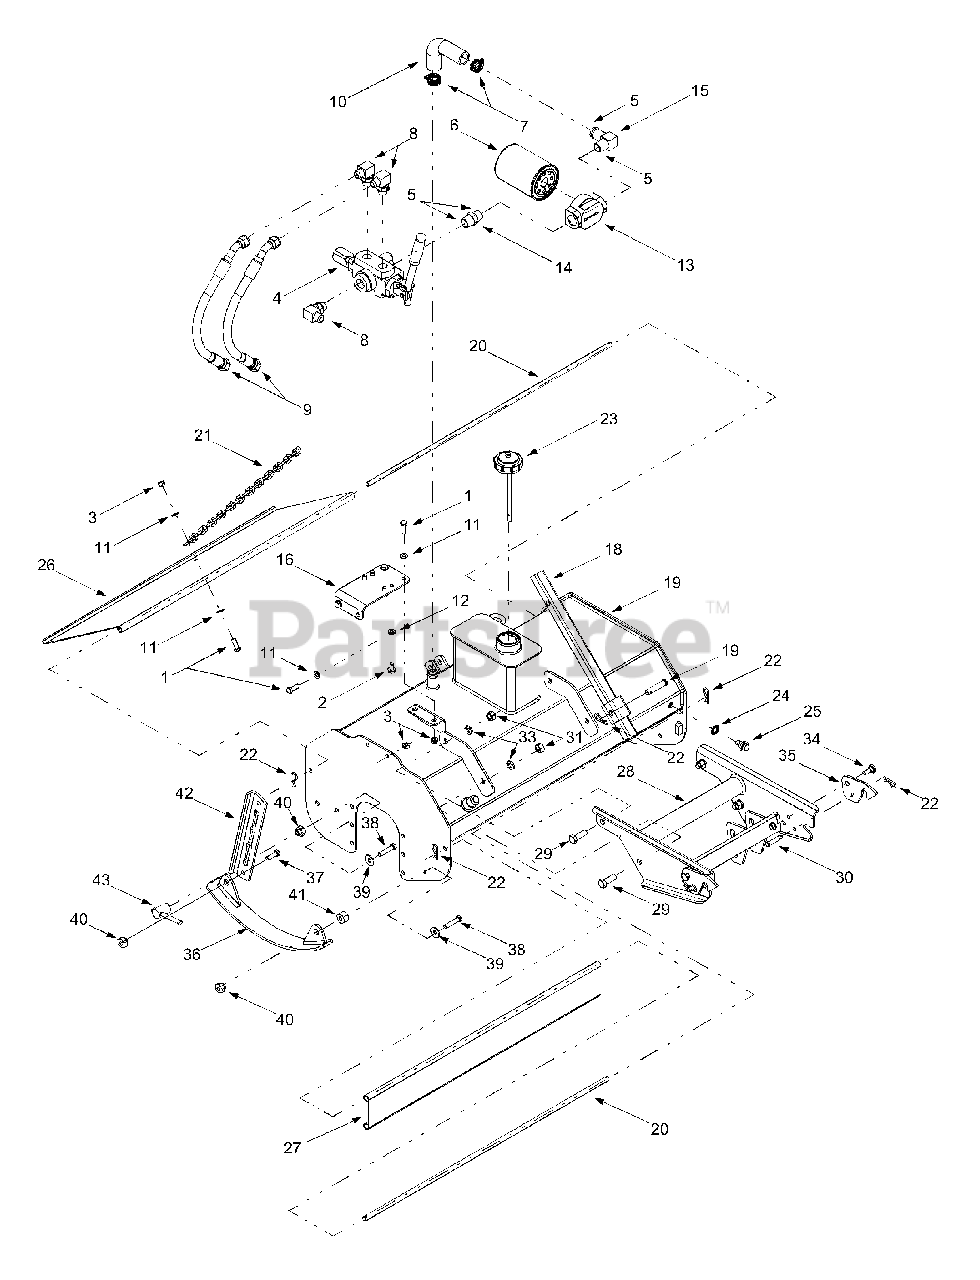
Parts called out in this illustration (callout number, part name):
1	Hex Cap Screw, 3/8-16 x 1.0
2	Shoulder Screw, 3/8-16 x .625
3	Hex Lock Nut, 3/8-16
4	Energy Hydraulic Valve
5	Locktite(R) Hydraulic Sealant
6	Oil Filter
7	Adjustable Hose Clamp
8	90 degree Hydraulic Adapter, 7/8
9	Hydraulic Hose, 7/8-14
10	90 degree Hydraulic Hose, 1.37 x 1.0
11	Flat Washer, .375 x .738 x .063
12	Lock Washer, 3/8
13	Filter Housing
14	Hydraulic Adapter, 3/4 x 3/4
15	90 degree Hydraulic Adapter, 1.0 x 1.0
16	Valve Mounting Bracket
18	Tiller Stand
19	Clevis Pin, .50 x 2.0
21	Chain, 24.37"
22	Internal Cotter Pin
23	Vented Tank Cap
24	Stat-O-Seal O Ring
25	Drain Plug
30	Clevis Pin, 3/8 x 1.75
31	Hex Nut, 1/2-13
33	Lock Washer, 1/2
34	Shoulder Screw, .50 x .27, 3/8-16
34	Flange Lock Nut, 3/8-16
35	Hitch Latch
36	Skid Bracket Assembly
37	Hex Cap Screw, 3/8-24 x 1.0
38	Hex Cap Screw, 3/8-24 x 1.75
39	Bell Washer, .396 x 1.14 x .095
40	Shoulder Nut, 3/8-24
41	Spacer, 1.0 x .380 x .64
42	Skid Adjuster Bracket
43	Adjuster Crank
